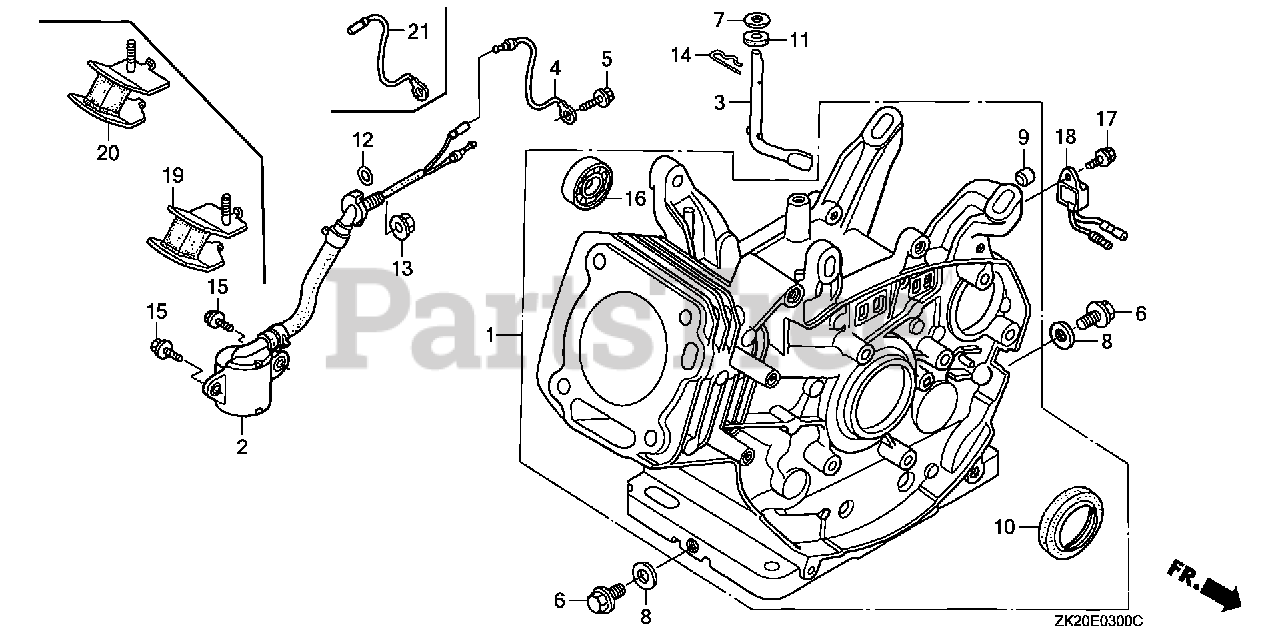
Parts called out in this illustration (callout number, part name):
1	CYLINDER ASSY. (BALANCER+ALERT)
2	SWITCH ASSY., OIL LEVEL
3	SHAFT, GOVERNOR ARM
6	BOLT, DRAIN PLUG (12X15)
7	WASHER (8.2X17X0.8)
8	WASHER, DRAIN PLUG (12MM)
10	OIL SEAL (30X46X8)
12	O-RING (14MM) (ARAI)
12	O-RING (14MM) (NOK)
13	NUT, FLANGE (10MM)
14	PIN, LOCK (10MM)
15	BOLT, FLANGE (6X12)
16	BEARING, RADIAL BALL (6202)
17	BOLT, FLANGE (6X12) (CT200)
18	ALERT UNIT, OIL
